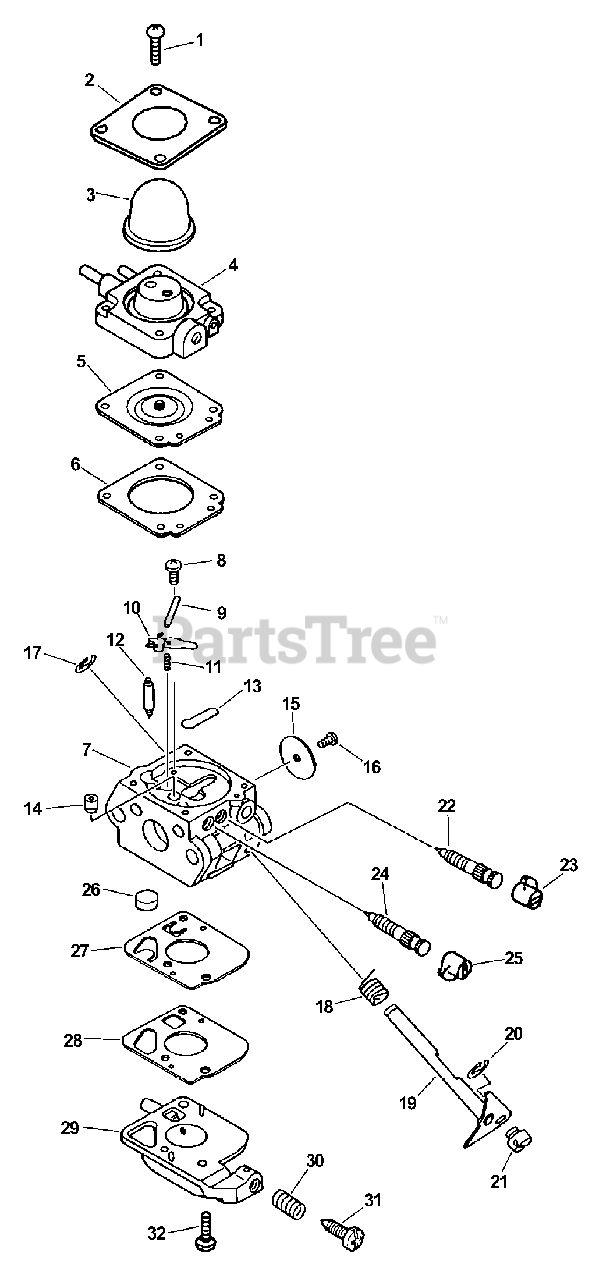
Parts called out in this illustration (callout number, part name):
2	RETAINER, PURGE BULB
3	BULB, PURGE
4	BASE, PURGE
5	DIAPHRAGM, METERING
6	GASKET, METERING
7	BODY, CARBURETOR
9	PIN, METERING LEVER
10	LEVER, METERING
11	SPRING, METERING LEVER
12	VALVE, INLET NEEDLE
13	PLUG, WELCH
14	NOZZLE, CHECK VALVE
15	VALVE, THROTTLE
18	SPRING, THROTTLE RETURN
19	SHAFT, THROTTLE
22	NEEDLE, MIXTURE
23	CAP, LIMITER - WHITE
24	NEEDLE, HIGH SPEED
25	CAP, LIMITER - RED
26	STRAINER
27	DIAPHRAGM, PUMP
28	GASKET, PUMP
29	COVER, FUEL PUMP
31	SCREW, THROTTLE ADJUST
